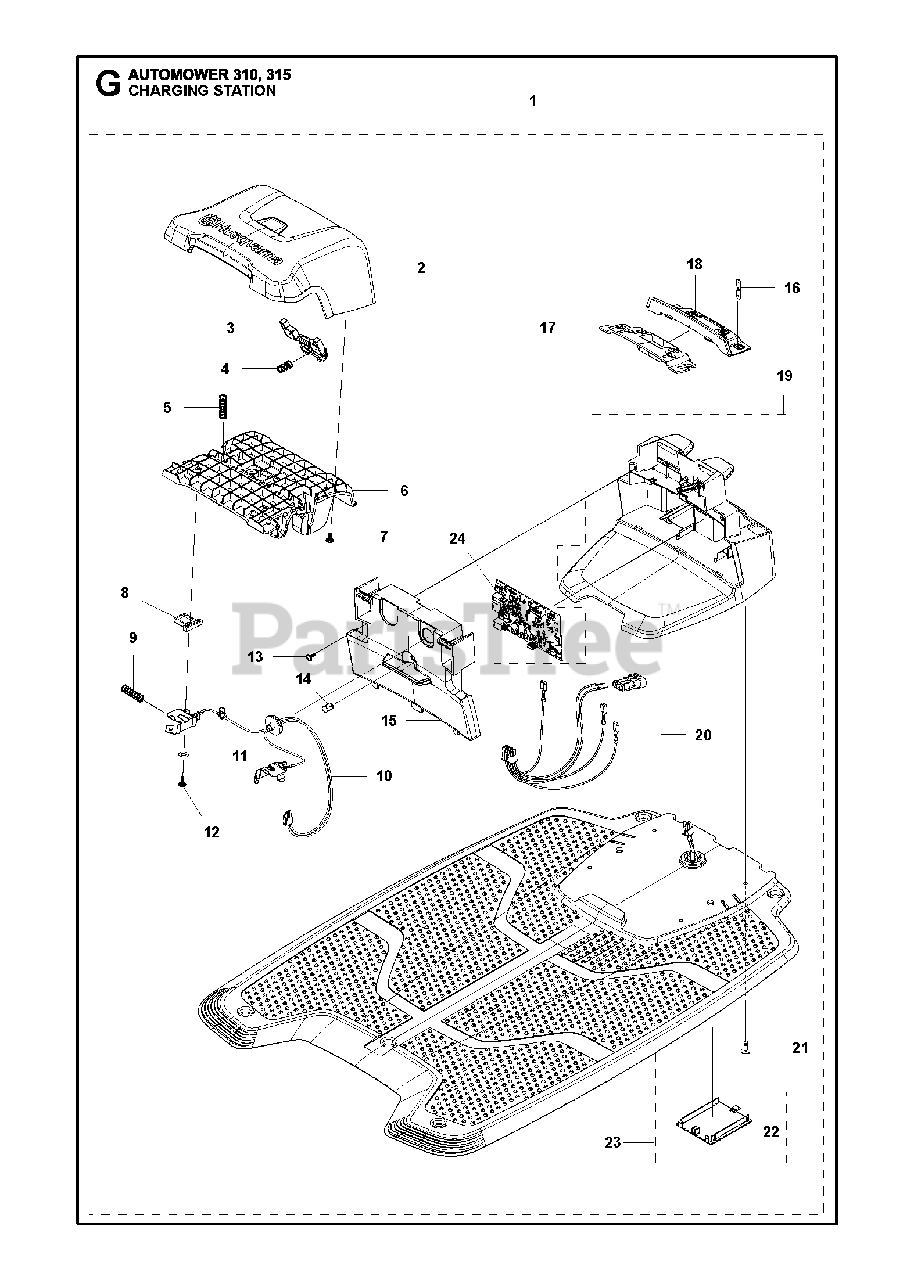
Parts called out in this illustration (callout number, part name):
1	CHARGING STATION ASSY HUSQVAR
2	CAP CHARGING STATION
3	BUTTON CHARGING STATION, RELEA
4	SPRING STOP BUTTON
5	SPRING SPRING CAP
6	FRAME CHARGING STATION
7	SCREW 14MM
8	DISTANCE CHARGING STATION
9	SPRING SPRING CAP
10	Cable Assembly, Charging Contacts
11	WASHER
12	SCREW 14MM
13	SCREW 14MM
14	LENS
15	LID CHARGING STATION
16	TERMINAL TERMINAL CHARGING STA
17	PAN CHARGING STATION 320, ONE
18	HOLDER CHARGING STATION
19	HOUSING ASSY CHARGING STATION
20	LOOM KIT GENERATOR BOARD
21	SCREW 14MM
22	COVER CHARGING PLATE
23	CHARGING PLATE KIT
24	PRINTED CIRCUIT ASSY PCBA CS B
